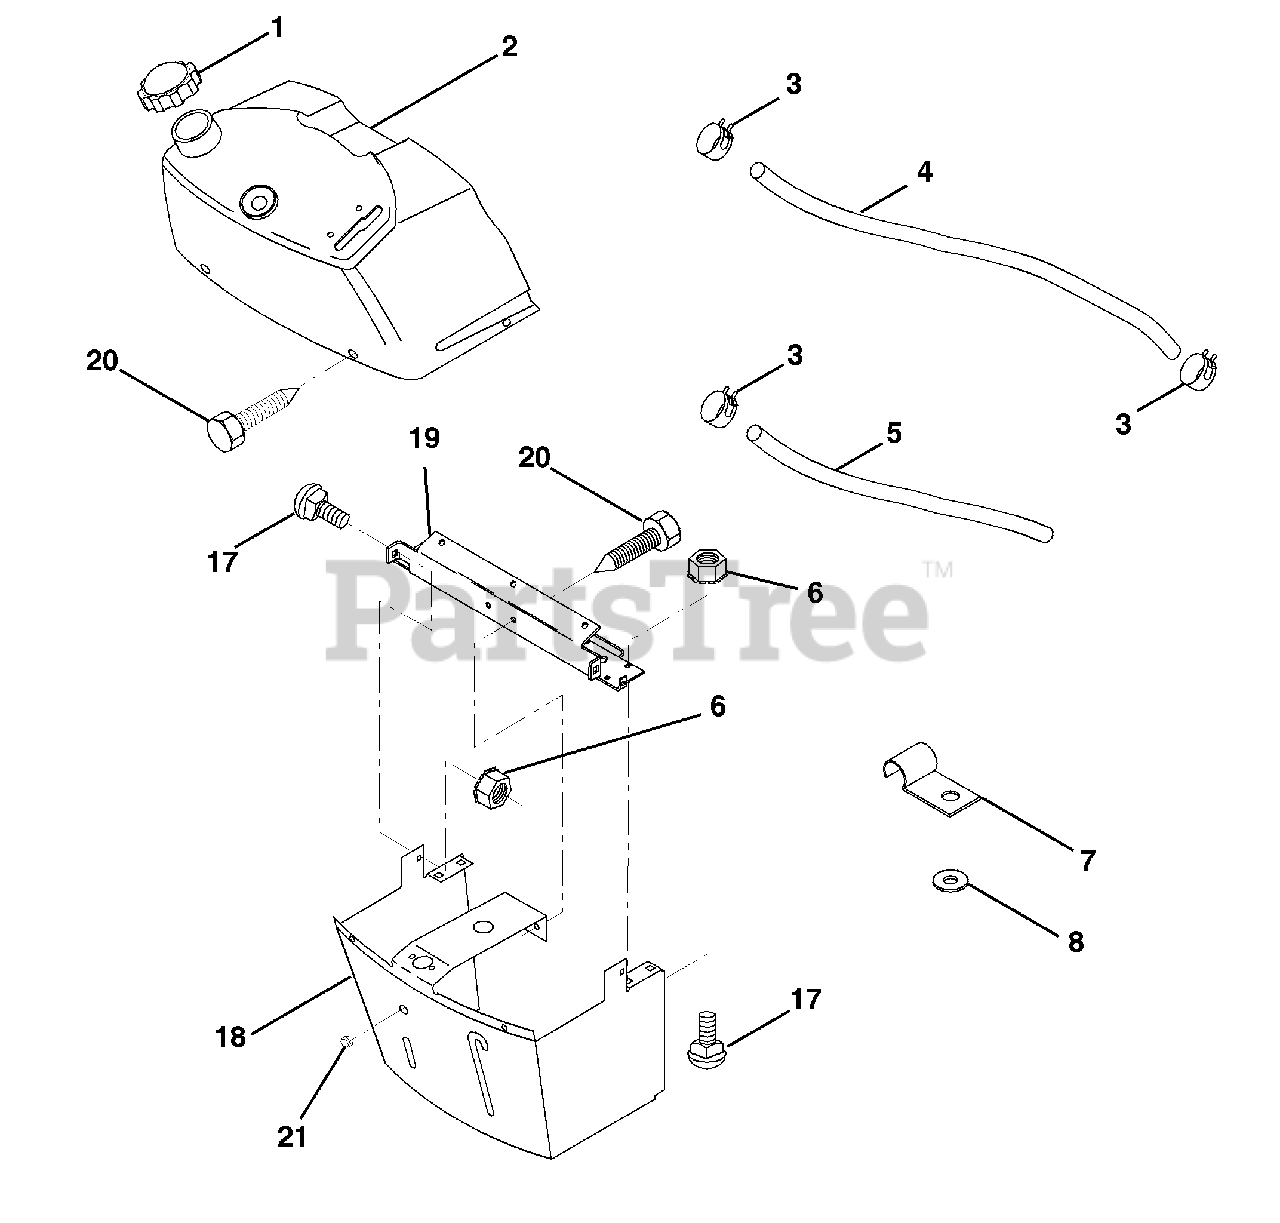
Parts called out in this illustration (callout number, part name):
1	Cap, Fuel Tank
2	Assembly, Dash & Fuel Tank
3	Clamp, Hose
4	Line, Fuel
5	Line, Fuel
6	Nut, Keps Blk Hex 1/4-20
7	Clip, Fuel Line
8	Washer 9/32 x 3/4 x 16 Gauge
17	Bolt, Carriage 1/4-20 x 1/2 Grade 5
18	Support Assembly, Dash
19	Brace, Cross
20	Screw, Self-Tapping 1/4-20 x 1/2
21	Plug, Dome, Black
